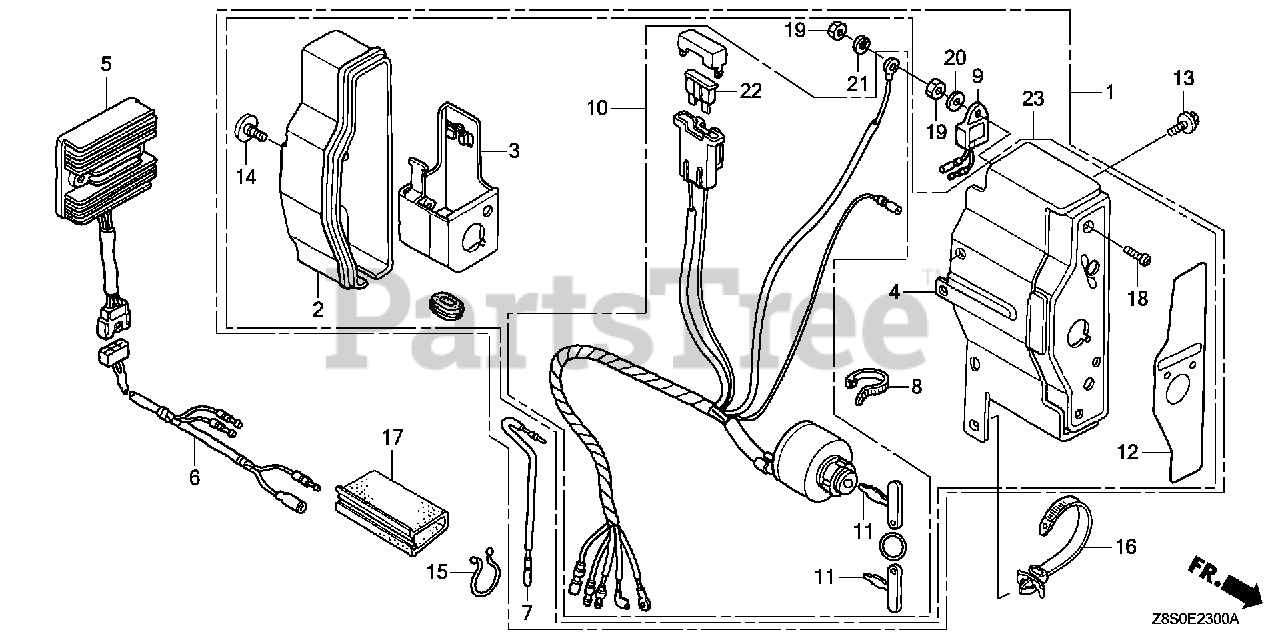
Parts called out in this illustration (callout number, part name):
2	CASE, CONTROL
3	BRACKET, CASE MOUNTING
4	PANEL, CONTROL *NH1* (BLACK)
4	PANEL, CONTROL *R280* (POWER RED)
5	RECTIFIER ASSY., REGULATOR (20A)
6	SUB-WIRE HARNESS ASSY.
8	BAND
10	SWITCH ASSY., COMBINATION (18A)
11	KEY
12	MARK, CONTROL BOX (EXP)
13	BOLT, FLANGE (6X12) (CT200)
14	SCREW, SPECIAL (6X12)
15	CLIP, PURSE LOCK
16	STRAP, CABLE (118MM) *NH1L* (Honda Code 1170653). (BLACK)
17	TUBE, FASTENER (30)
18	SCREW, PAN (4X12)
19	NUT, HEX. (4MM)
21	WASHER, SPRING (4MM)
22	FUSE, BLADE (15A)
22	FUSE, BLADE (25A)
23	BOX ASSY., CONTROL (18A) *NH1* (EXP) (BLACK)
23	BOX ASSY., CONTROL (18A) *R280* (EXP) (POWER RED)
